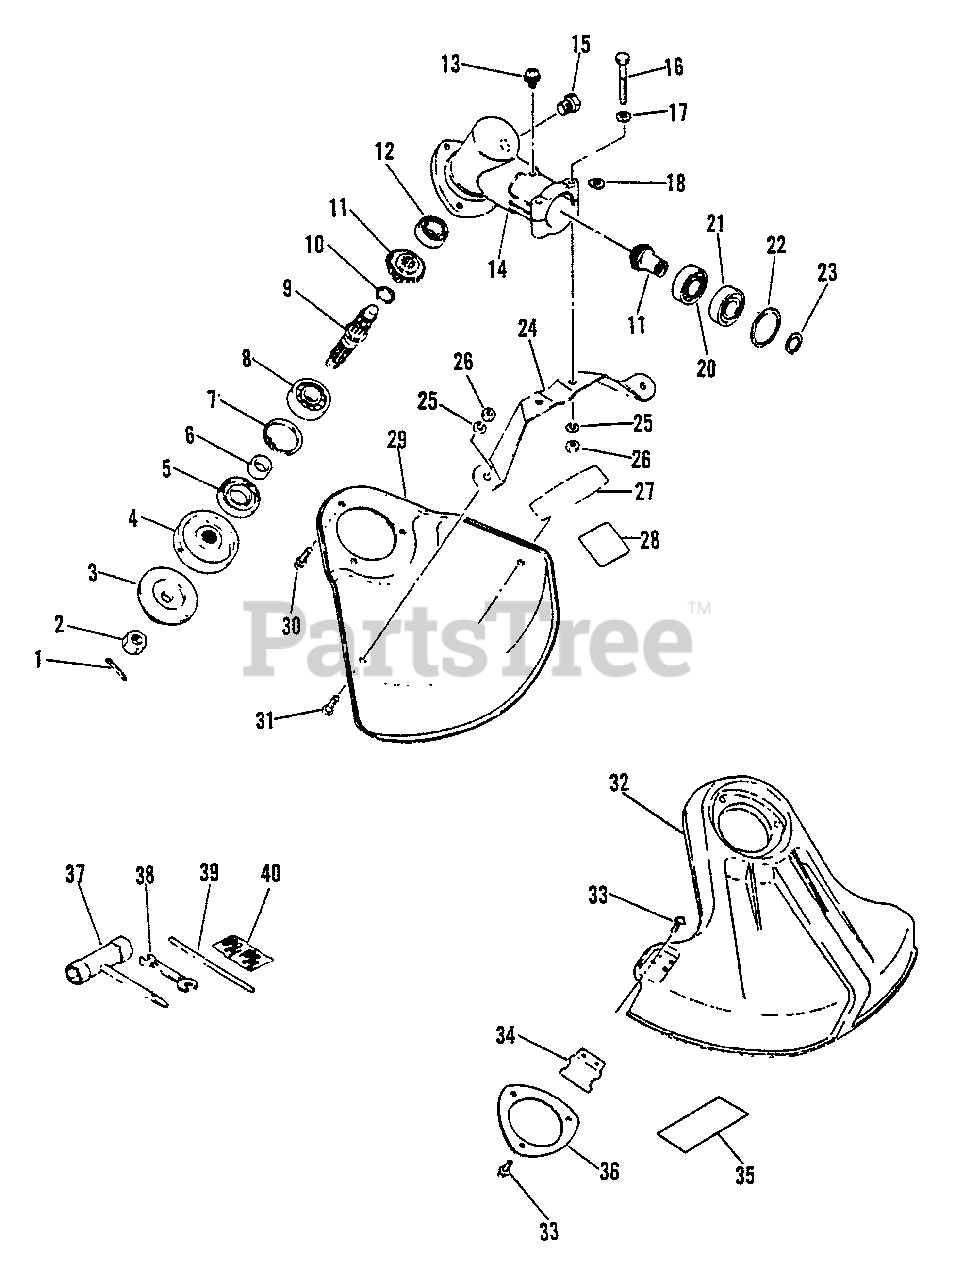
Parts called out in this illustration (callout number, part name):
1	PIN, COTTER 2×22
3	PLATE, ADAPTOR - LOWER
4	PLATE, ADAPTER - UPPER
5	SEAL, OIL 22
6	SPACER 11.8×15×9
7	RING, SNAP Ø32
8	BEARING, BALL - 6201 C3
9	SHAFT, GEAR
10	RING, SNAP Ø12
11	GEAR SET
12	BEARING, BALL 6000
13	SCREW 5×10
14	CASE, GEAR
15	BOLT 8×8 SP
16	BOLT 5×40
17	WASHER, FLAT 5.5×10×0.8
20	BEARING, BALL 6001
21	BEARING, BALL 6001
22	RING, SNAP 28
23	RING, RETAINING - 12
24	BRACKET, SHIELD MOUNTING
25	WASHER, SPRING 5
26	NUT M5
27	LABEL, ECHO
28	LABEL - CAUTION
29	DEBRIS SHIELD KIT - BLADE
30	SCREW 5×10
31	SCREW 5×8
32	SHIELD ASSY
33	SCREW 5×16
34	CUTTER, LINE
35	LABEL, CAUTION
36	PLATE, SHIELD Ø49.5 MM
37	T-WRENCH 17x-19 L200
38	SPANNER 8×10
39	TOOL, LOCKING 5×120 MM
40	PIN, COTTER 2×22 (PKG. OF 10)
